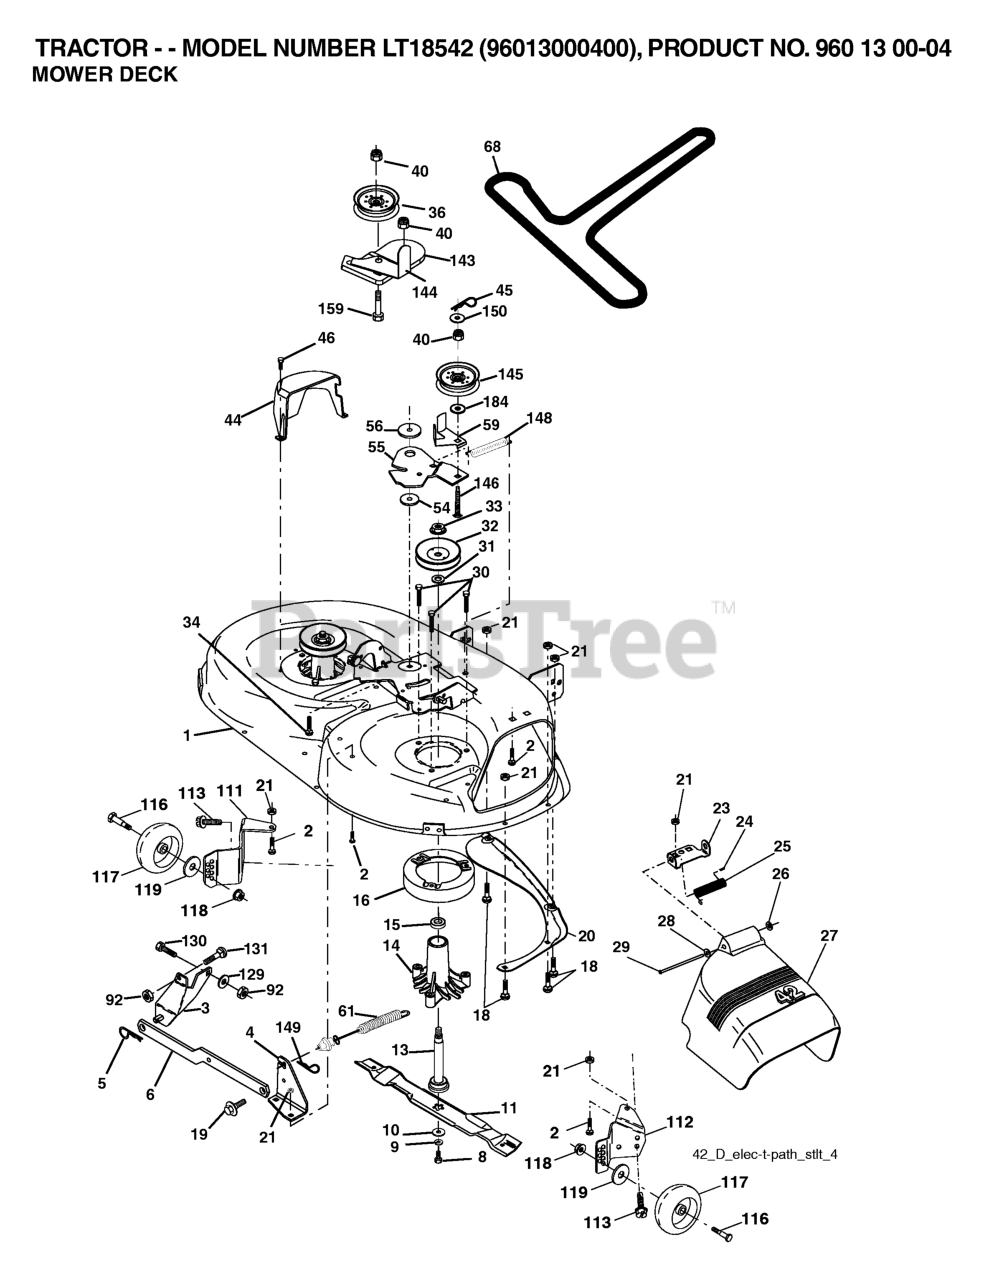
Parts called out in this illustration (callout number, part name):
1	42" DECK KIT
2	RP BOLT 5/16-18 X3/4 ZN/YEL GR
3	BRKT ASM SWAY BAR
4	BRACKET SWAY BAR 42" DECK
5	RETAINER-SPRNG RB
6	BAR SWAY DECK
8	BLADE BOLT
9	LOCKWASHER
10	WASHER.BLADE
11	42" HI-LIFT BLADE
13	SHAFT ASM VENT
14	HOUSING.MANDREL.VENTED (MACHD)
16	STRIPPER.MANDREL.ROUND.BLACK
18	BOLT
19	BOLT SHD 5/16-18
20	BAFFLE.VORTEX
21	LOCKNUT
23	BRKT, DEFL. MOWER
24	CAP-SLEEVE LT
25	SPRING TORSION
26	NUT PUSH M
27	SHIELD DEFLECTOR
28	Washer 11/32 x 5/8 x 16 Ga SD
29	ROD.HINGE
30	SCREW, WASHER HEAD
31	WASHER.SPACER.MANDREL
32	PULLEY/MANDREL
33	NUT, FLG TOPLOCK 9/16"
34	BOLT.3/8-16X1.50
36	FLAT IDLER PULLEY
40	NUT LOCK FLG 3/8-16 UNC
44	GUARD MANDREL LH BLACK
45	RETAINER M
46	SCREW.1/4-20X5/8
52	BOLT.SHOULDER.5/16-18
53	ARM BRAKE ASSY
55	ARM IDLER 42" MOWER LT/YT
56	SPACER.RETAINER.MOWER
59	GUARD, BELT
67	KNOB T (3/8 HOLE)
68	BELT V SECONDARY
92	NUT
111	BRACKET, WHEEL
112	BRACKET, WHEEL
113	BOLT.5/16HEX.WHS.HD
116	BOLT M
117	WHEEL.GAGE.HALF.SPOKED
118	LOCKNUT
119	WASHER.5/16.FLAT.STE.STD.
129	WASHER
131	BOLT D
142	ARM SPRING BRAKE MOWER
143	BRACKET, ARM IDLER
144	DNO KEEPER.BELT.42".CLUTCH.CBL
145	PULLEY
146	BOLT, CARRIAGE IDLER BLACK
147	SPRING EXTENSION
148	IDLER RETURN SPRING
149	SPRING.RETAINER.YELLOW.ZINC
152	CLUTCH CABLE 42"
158	SCREW
184	WASHER
185	HEAD ASM. CABLE CLUTCH
